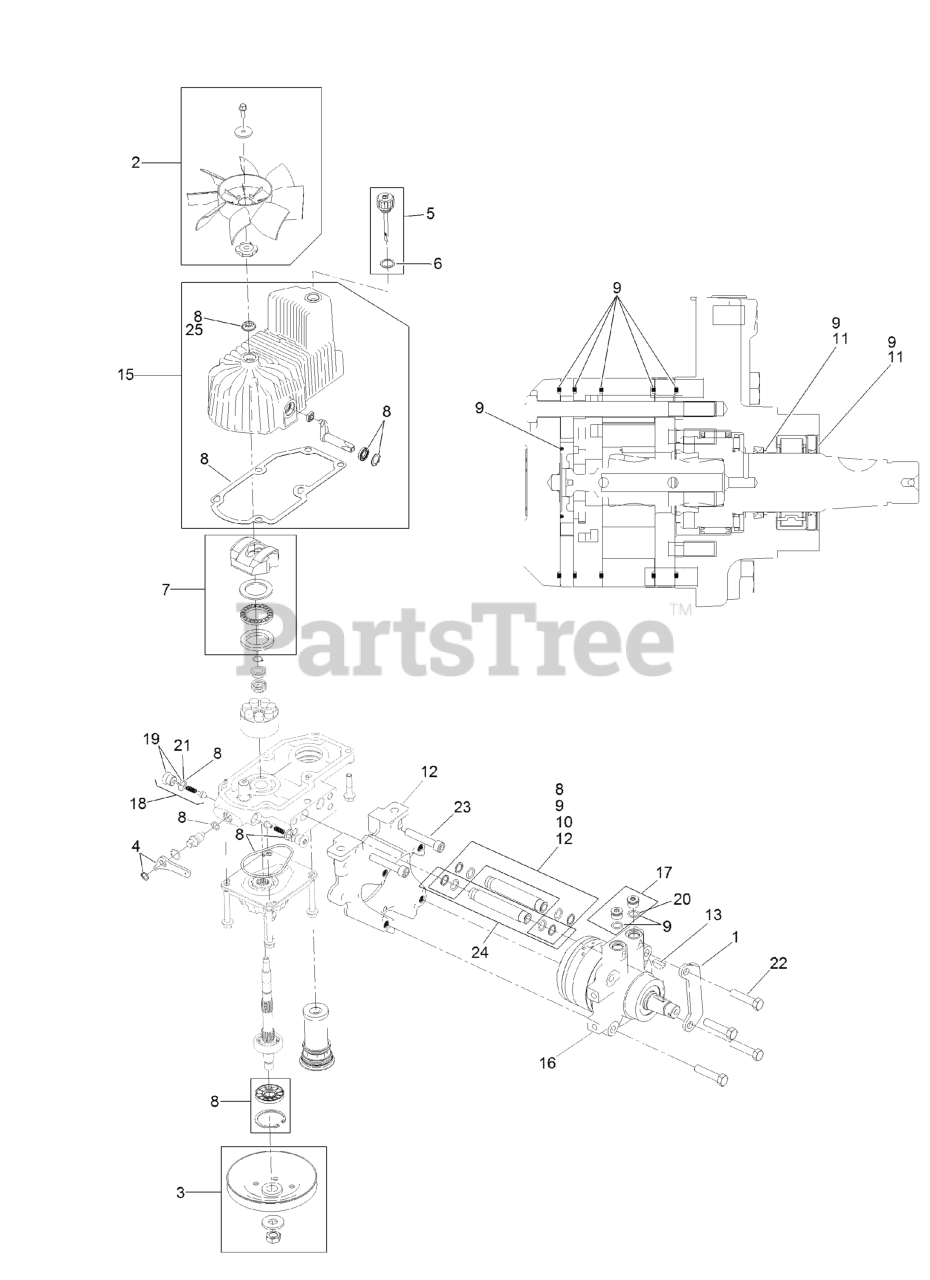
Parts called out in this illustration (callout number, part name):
1	MOUNT-SHOE, HORSE
2	FAN KIT
3	PULLEY KIT
4	HANDLE-BYPASS VALVE, HYDRO
5	DIPSTICK-HYDRO W/GASKET
6	GASKET-DIPSTICK, HYDRO
7	SWASH BLOCK KIT
8	PUMP SEAL KIT
9	MOTOR SEAL KIT
10	TUBE SEAL KIT
11	OUTPUT SHAFT SEAL KIT
12	NOSE CUP-UHT
13	KEY-WOODRUFF
15	HOUSING-HYDRO, RH
16	MOTOR-HYDRAULIC RH 240CC
17	MAGNETIC PLUGS SERVICE KIT
18	CHECK VALVE ASM
19	PLUG-CHECK (W/O-RING)
21	O-RING-CHECK VALVE
22	SCREW HH
23	SCREW-HSH
24	HYDRAULIC TUBE KIT
25	SEAL-FAN DRIVE
26	Kit, Pump Section 12Cc RH
27	KIT, ROTATING GRP 12CC RH
